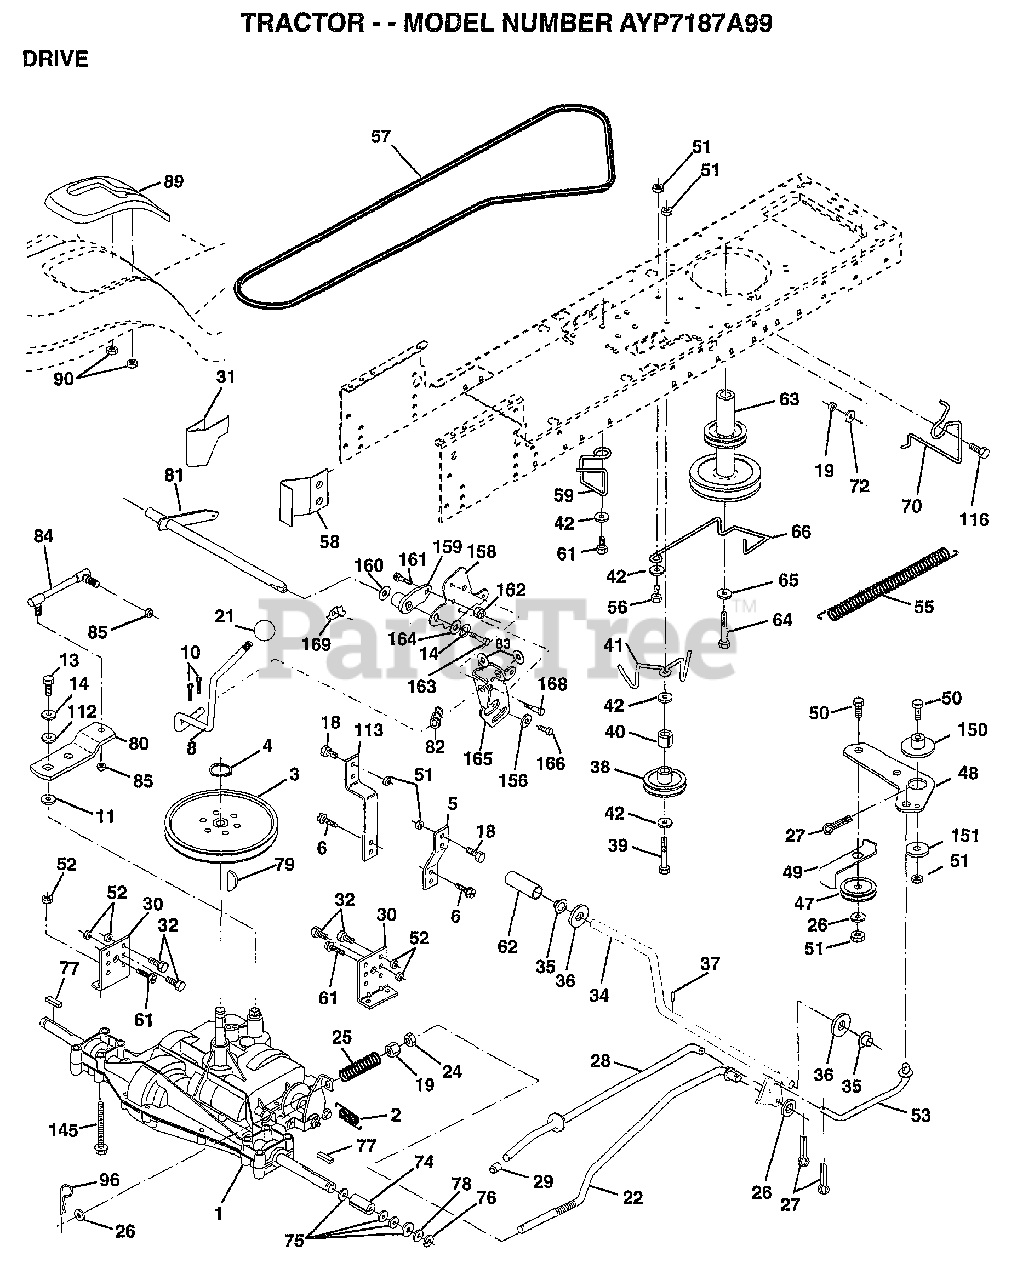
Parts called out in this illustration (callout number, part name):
2	SPRING.BRAKE.RETU
3	PULLEY TRANS
5	STRAP TORQUE
6	SCREW
8	RODL.SHIFT.FEND.ADJ.STLT
10	PIN COTTER 1/8
11	WASH-SHFT PLT LT
13	BOLT.1/4-28.W/PAT
14	LOCKWASHER
18	BOLT
19	NUT
21	KNOB T (1/2-HOLE)
22	BRAKE ROD
24	NUT
25	SPRING ROD LT
26	WASHER
27	COTTER PIN
28	ROD.BRAKE.PARK.LT
30	TRANSAXLE MTG BKT
31	"KEEPER,BELT LH T"
32	BOLT
34	SHAFT ASM-PEDAL F
35	NYLON BEARING
36	WASHER LT
38	FLAT IDLER PULLEY
39	BOLT
40	SPACER T
41	"KEEPER,BELT.IDLER FLAT"
42	WASHER
48	BELLCRANK.CLUTCH
49	RETAIN BELT
53	"LINK, CLUTCH T"
55	"SPRING, RETURN LT"
58	"KEEPER,BELT RH T"
59	KEEPER BELT CNTSP
61	SCREW
62	PEDAL COVER T
63	PULLEY.ENGINE
64	BOLT
65	LOCKWASHER
66	KEEPER-BELT
70	KEEPER BELT ENG
72	WASHER
74	SPACER AXLE
75	WASHER
76	E-RING LT
77	SQUARE KEY
78	WASHER
80	"ARM.SHIFT.20""TIRE"
81	SHAFT.ASM.CROSS
82	SPRING.SHIFT.STLT.GREY
83	WASHER
85	NUT.CNT.LOCK.1/4
89	CONSOLE.SHIFT.STLT.6SP.BLACK
90	NUT
96	RETAINER M
112	WASHER LT
113	"STRAP,TORQUE"
116	BOLT RDHD 3/8-16
145	BOLT.HEX.FLGHD
150	BUSHING.BELLCRANK.GRD.DR
151	WASHER
156	WASHER.SRRTD.5/16
158	BRKT.SHIFT.MOUNT
159	HUB.SHIFT
160	WASHER
161	BOLT T
164	WASHER.5/8X.281X10GA
165	BRKT.PIVOT.LEVER
166	SCREW.5/16-18X5/8
168	BOLT.SHOULDER.5/16-18X.561
169	PLATE.FASTENING
